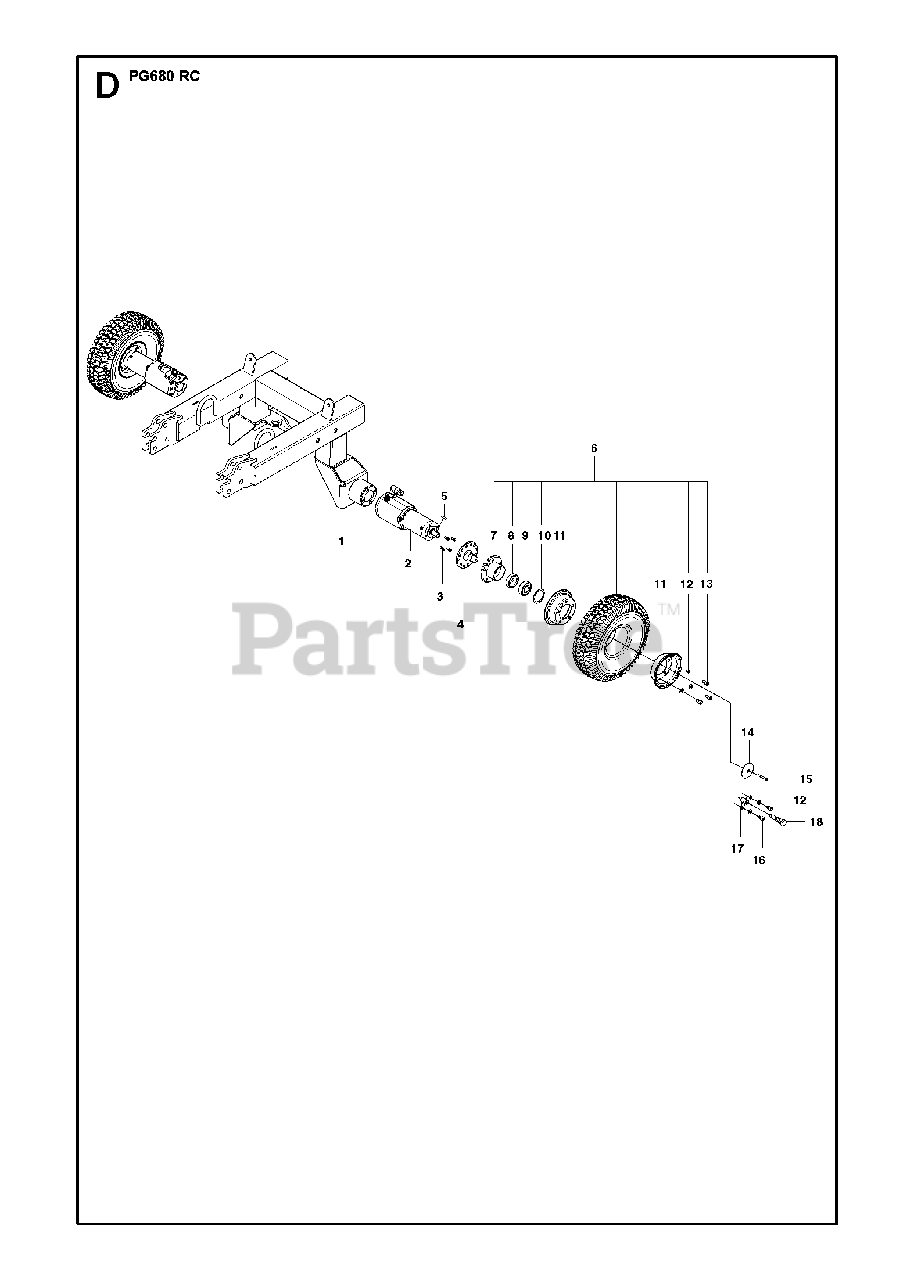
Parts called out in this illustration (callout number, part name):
9	BALL BEARING
10	CIRCLIP
12	WASHER
